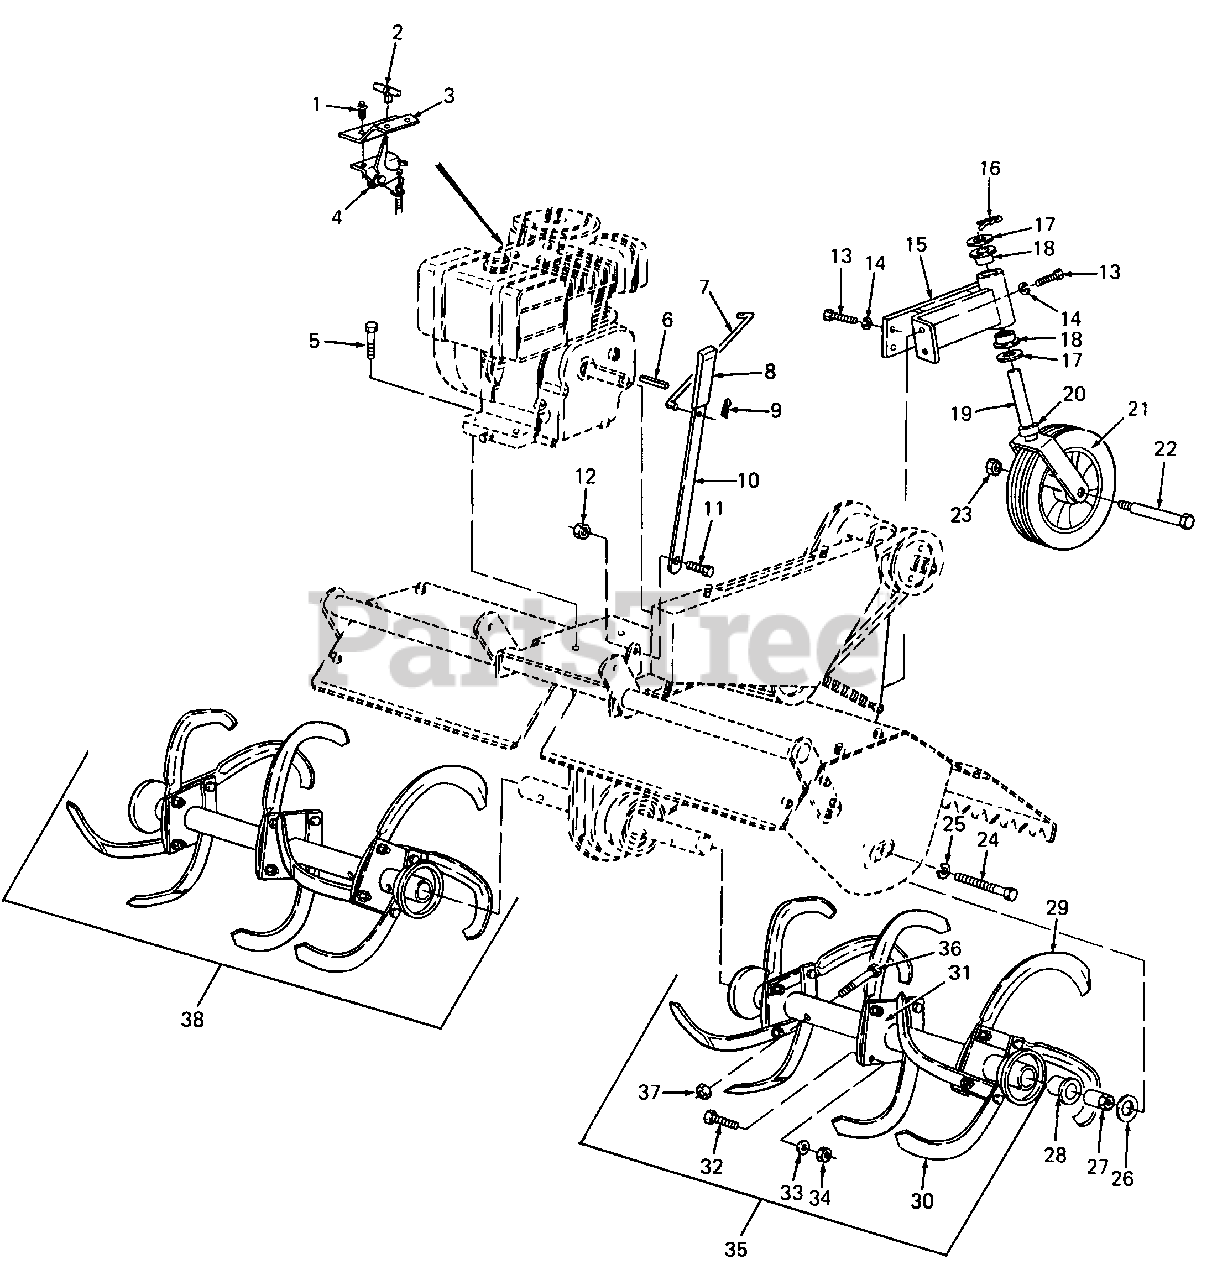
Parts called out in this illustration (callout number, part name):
1	Screw, Hex Wash Hd Tapp, #8 X .50 Lg
2	Knob, Throttle Control
3	Bracket, Throttle Control
4	Control Assy, Throttle
5	Screw, Hex Cap, 5/16-18 X 2.0 Lg
6	Key, Square, 1/4 X 2.0 Lg
7	Rod, Clutch
9	Pin, Cotter, 1/8 Dia X 1.0 Lg
12	Nut, Hex Center Lock, 3/8-16
13	Screw, Hex Wash Hd Tapp, 3/8-16 X .75 Lg
14	Washer, Lock, 3/8
17	Washer, Flat, .760 X 1.49 X .06 Thk HDN
18	Bearing, Flange
19	Caster, Swivel Wheel
22	Shoulder Bolt
23	Nut, Hex Center Lock, 7/16-14
24	Screw, Hex Cap, 3/8-16 X 1.25 Lg
25	Washer, Lock, 3/8
26	Washer, Thrust, 1/2 X 1.55 OD
28	Bearing, Flange
29	Tine, L.H., 14" X 5/16"
33	Washer, Lock, 3/8
34	Nut, Hex, 3/8-24
35	L.H. Tine Assy
36	Screw, Hex Cap, 7/16-14 X 2.0 Lg
37	Nut, Hex Center Lock, 7/16-14
